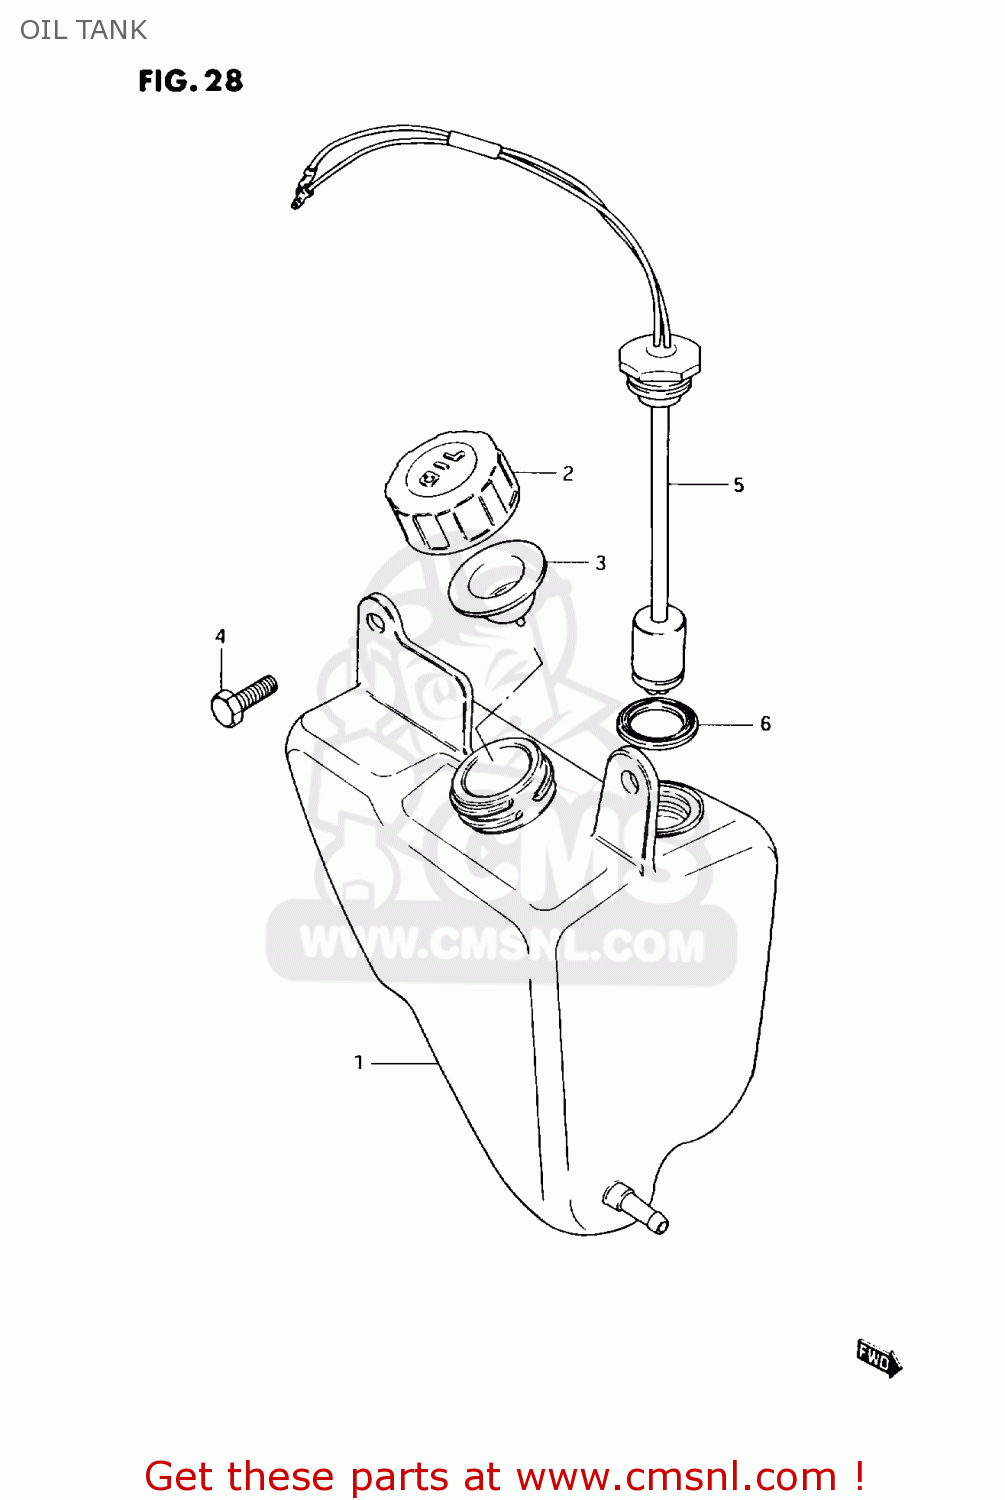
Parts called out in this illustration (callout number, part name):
1	TANK,OIL
2	CAP,OIL TANK
3	GASKET SET (NAS)
4	BOLT(6X16)
5	SWITCH ASSY,OIL LEVEL
6	GASKET (NAS)
